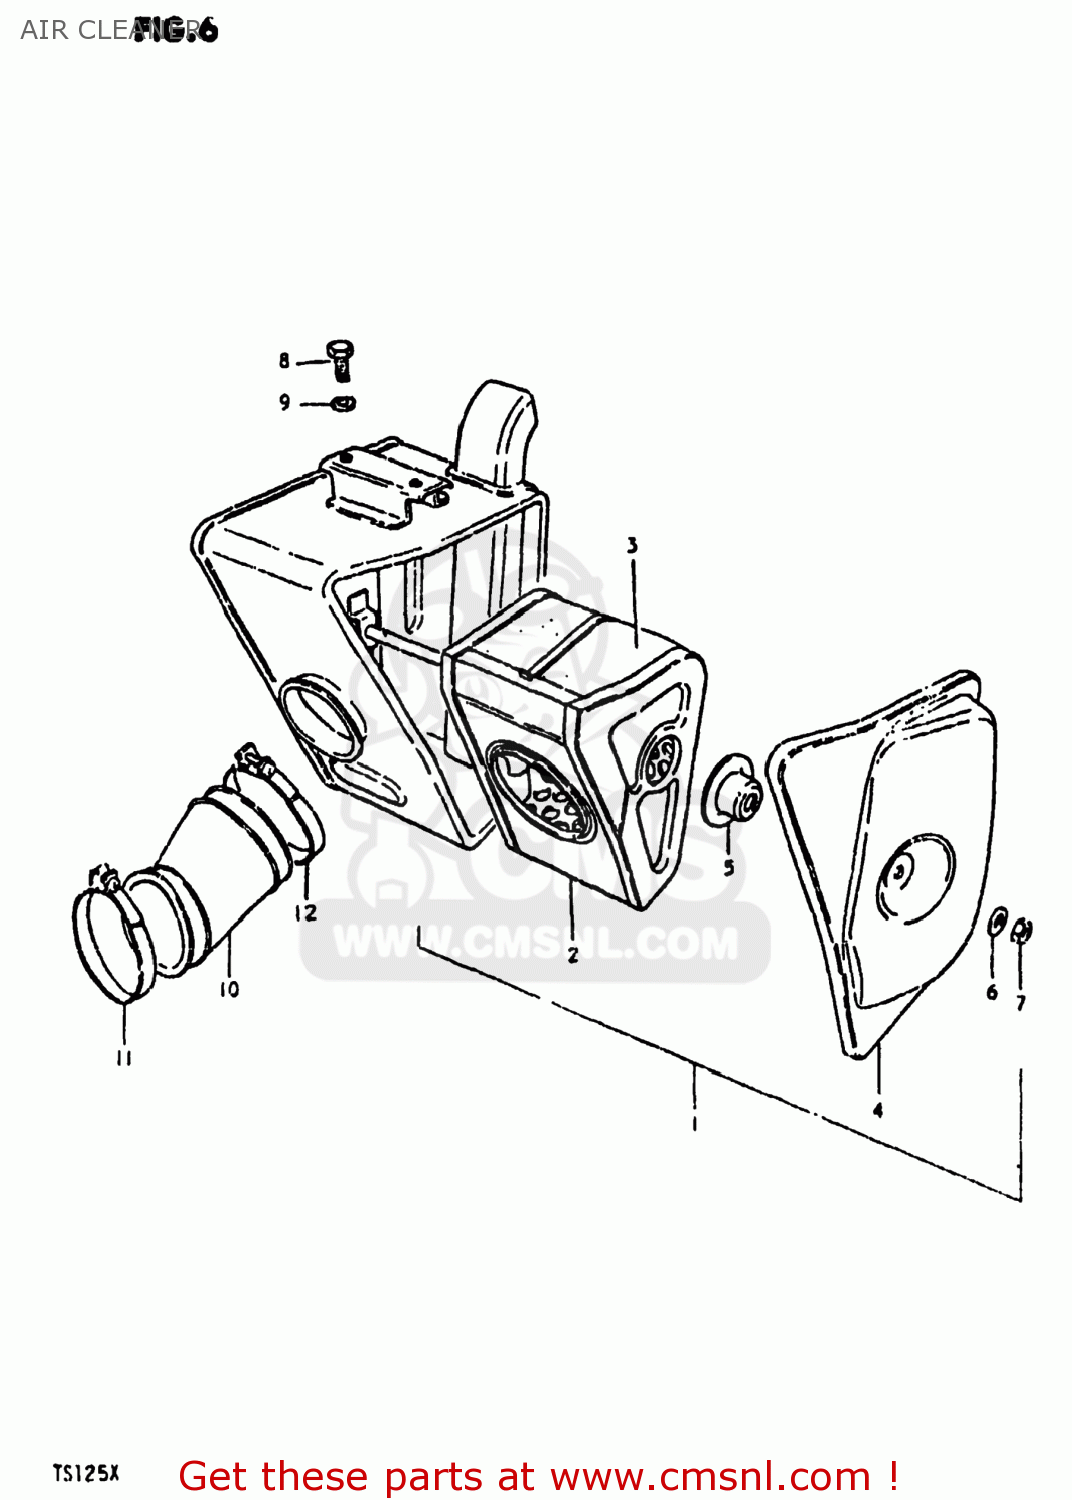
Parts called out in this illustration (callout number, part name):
1	CLEANER ASSEMBLY,AIR
2	FILTER ASSY,AIR CLEANER
3	FILTER
4	CAP
5	SPACER
6	WASHER
7	NUT
8	BOLT
9	WASHER
10	HOSE,CARBURETOR AIR INLET
11	CLAMP
12	CLAMP
